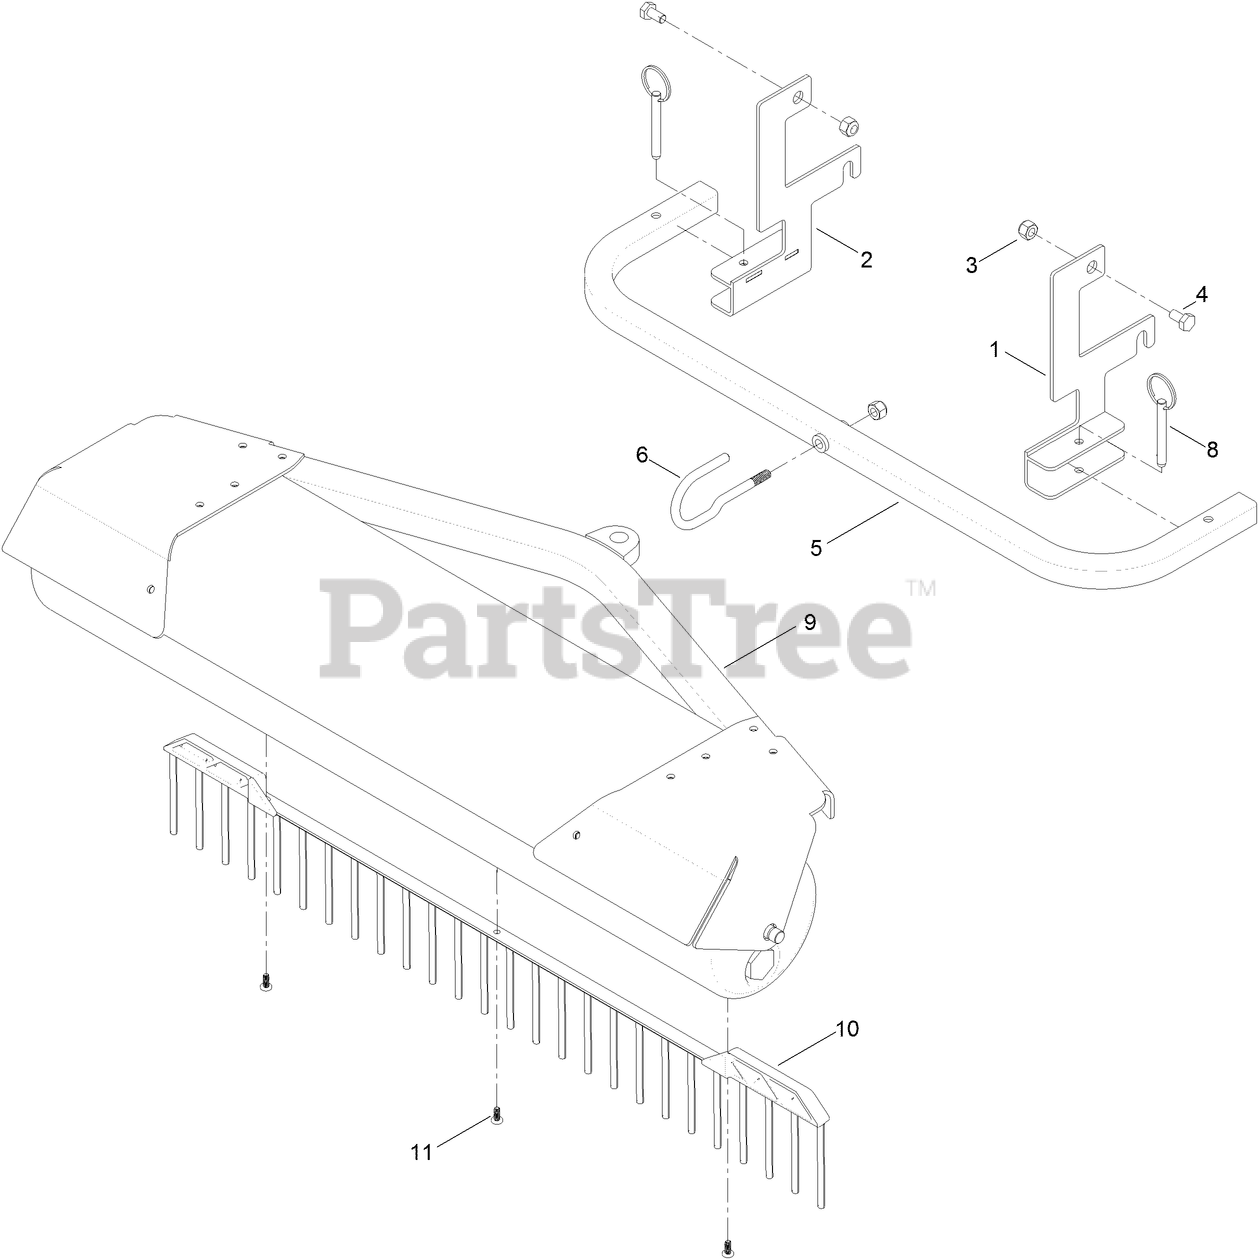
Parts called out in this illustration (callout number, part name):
1	MOUNT-RH
2	MOUNT-LH
3	NUT-LOCK, NI
4	SCREW-HH
8	PIN-SPRING
9	TRAILER-STRIPER, LAWN
11	SCREW-PPH
